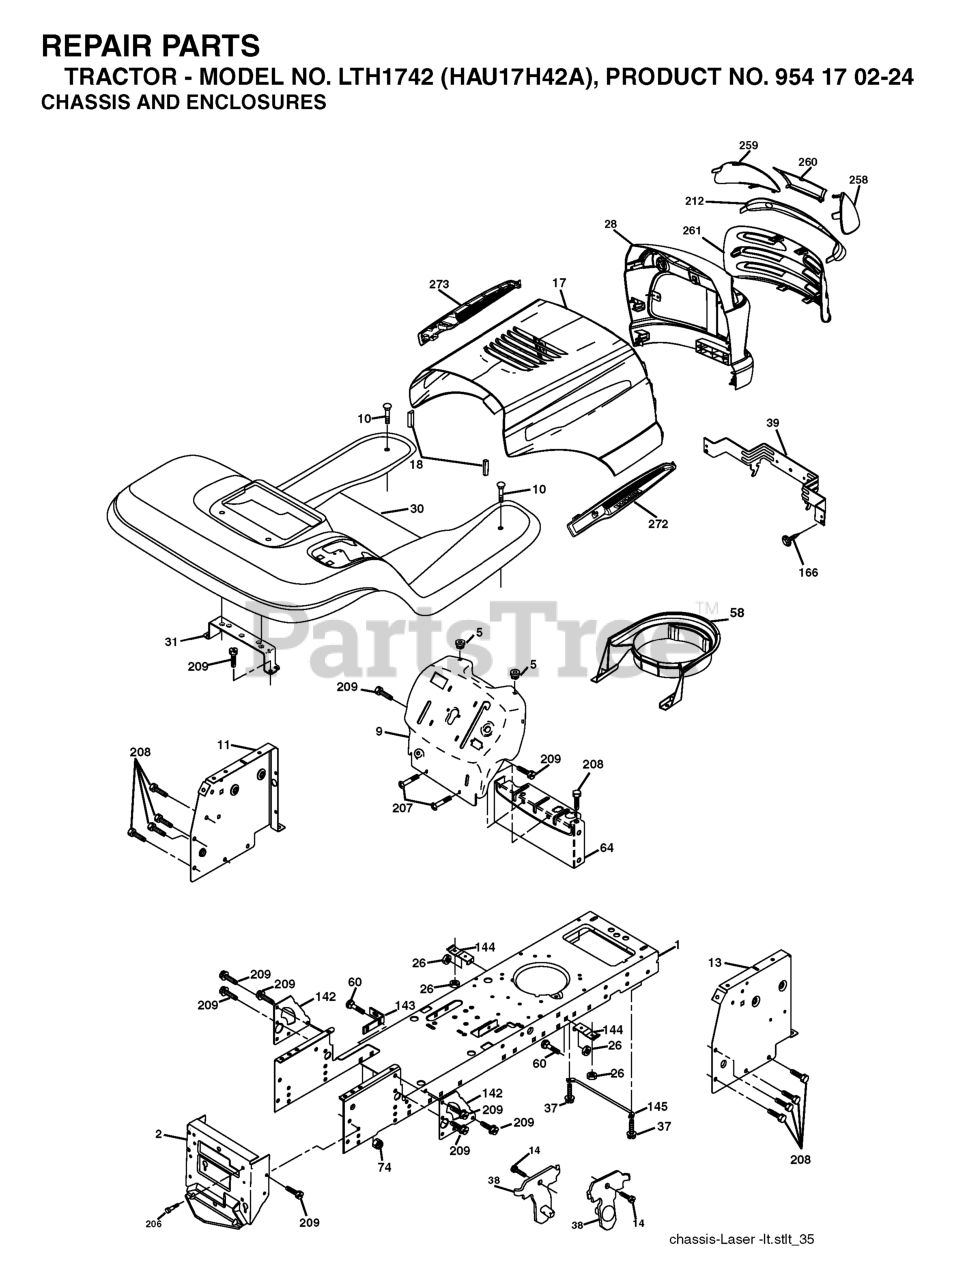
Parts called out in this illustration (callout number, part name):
1	CHASSIS STAMPING
2	DRAWBAR, 12GA
5	BUMPER.RUBBER.HOOD
9	DASH
10	BOLT D
11	PANEL.DASH.LH.LTX
13	PANEL DASH RH
14	SCREW LT
17	VENT.HOOD.LASER.III
18	BUMPER.HOOD.LARGE.1.75"
26	NUT
30	FENDER FOOTREST
31	BRACKET.SUPPORT.FENDER
37	Screw 5/16-18 x 1/2 Hex, Self Tapping 5/16-18 x 1/2
38	BRACKET.ASM.PIVOT.MOWER.REAR
39	BRACKET PIVOT LASER
60	Bolt - Rd. Hd. Sq. Neckiage 3/8 16 x 3/4
64	DASH LOWER
142	PLATE REINFORCEMENT
143	BRACKET, SWAYBAR CHASSIS
144	BRKT, FOOT REST
145	ROD PIVOT CHASSIS/HOOD
166	SCREW
206	SHOULDER BOLT 5/16-18TT
207	SCREW, 5/16-18 X 1/2
208	SCREW 3/8-16X1/2
209	SCREW, 3/8-16X3/4
212	INSERT.LENS.REFLECTIVE
258	LENS LH
259	LENS LH
260	COVER.LENS.HUSQ.( HAVE GRAY)
261	INSERT GRILLE
272	VENT.HOOD.LASER.
273	VENT.HOOD.LASER.
